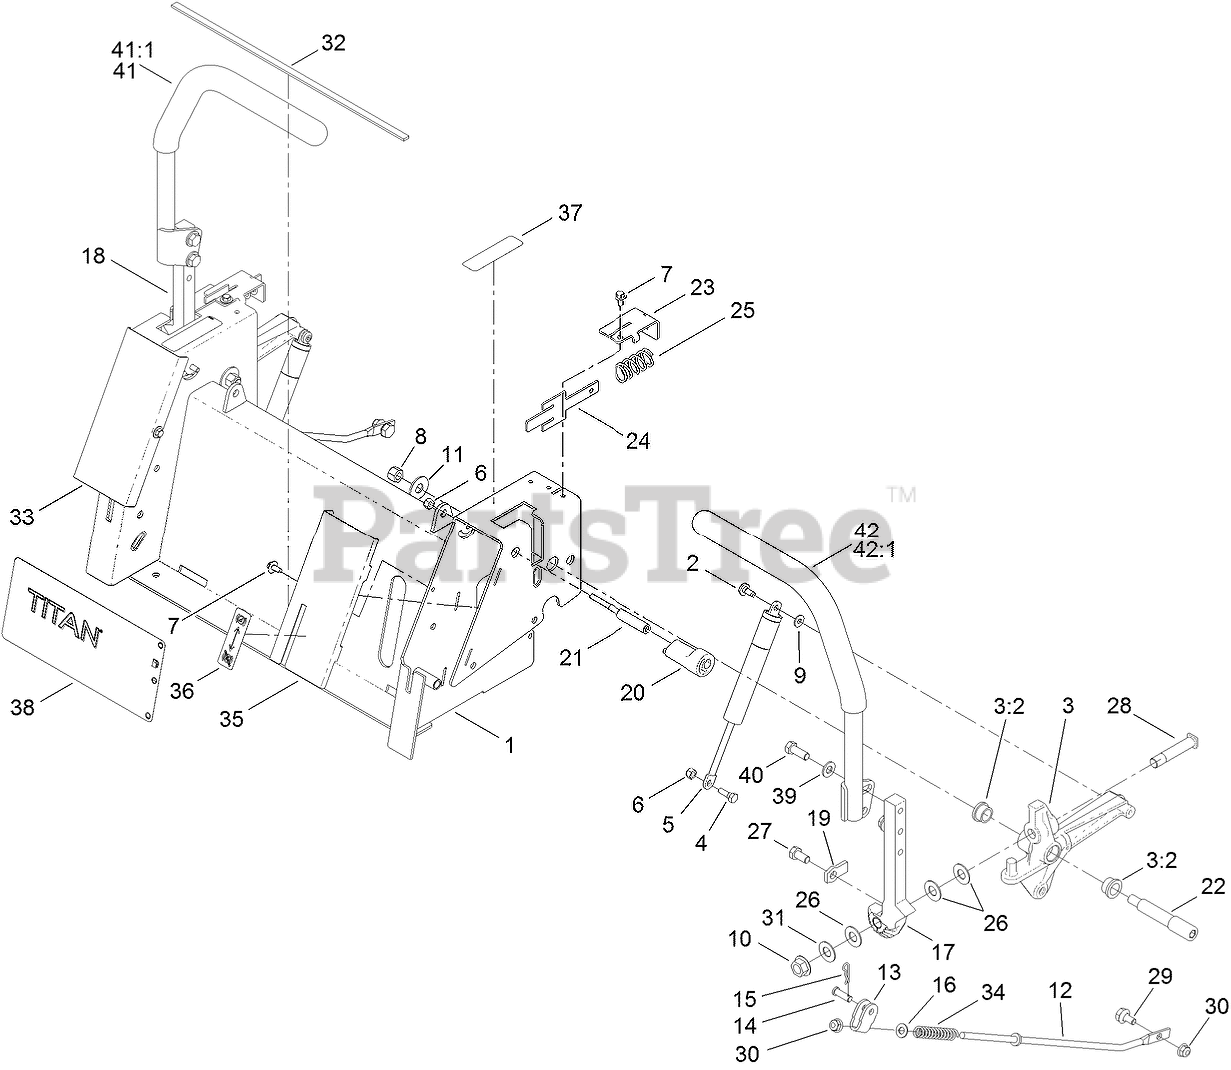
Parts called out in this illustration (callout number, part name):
1	BOX-CONTROL
2	SCREW-SHOULDER
3	ACTIVATOR ARM ASM
3:2	BUSHING
4	BOLT-SHOULDER
5	DAMPER-CONTROL, MOTION
6	NUT-LOCK, NI
7	SCREW-HHFTF
8	NUT-LOCK, NI
9	WASHER
10	NUT-HF
11	WASHER-FLAT
12	ROD-CONTROL
13	BRACKET-CONTROL
14	PIN-CLEVIS
15	PIN-COTTER
16	WASHER-PLAIN
17	ARM-ACTUATOR, LH
18	ARM-ACTUATOR, RH
19	TAB-STOP
20	ECCENTRIC
21	SCREW-ECCENTRIC
22	BOLT-SHOULDER
23	BRACKET-RETURN
24	PLATE-RETURN
25	SPRING-COMPRESSION
26	WASHER-PIVOT
27	SCREW-HH
28	BOLT-SHOULDER
29	BOLT-SHOULDER
30	NUT-HF, NI
31	WASHER-TEFLON
32	STRIP-VIBRATION, ANTI
33	COVER-CONTROL, RH
34	SPRING-RETURN, NEUTRAL
35	COVER-CONTROL, LH
36	DECAL-BRAKE, PARKING
37	DECAL-CONTROL, MOTION
39	WASHER-FLAT
40	SCREW-HH
41	RH LEVER/GRIP ASM
41:1	Grip-Control, Motion
42	LH LEVER/GRIP ASM
42:1	Grip-Control, Motion
